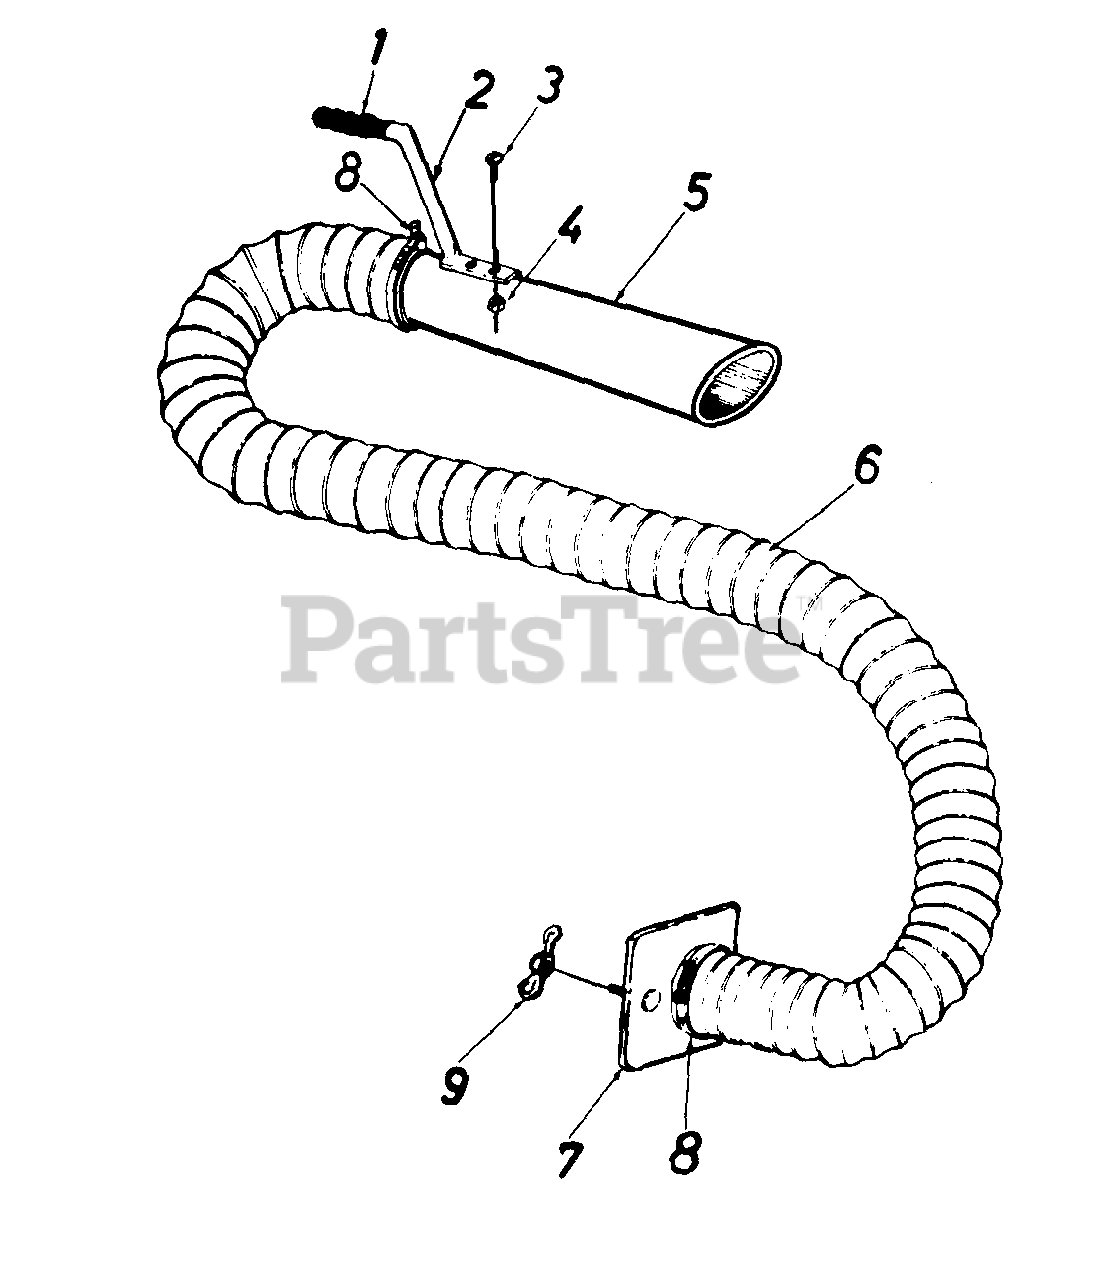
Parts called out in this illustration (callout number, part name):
1	Handle Grip
2	Handle
3	Truss Sems Scr. 10-24 x 1/2" Lg.
4	Hex Nut 10-24 Thd.
5	Hose Nozzle
6	Flexible Hose 4" Dia. x 10' Lg.
7	Hose Adapter Plate
8	Hose Clamp - For 4" Dia. Hose
9	Wing Nut 1/4-20 Thd.
